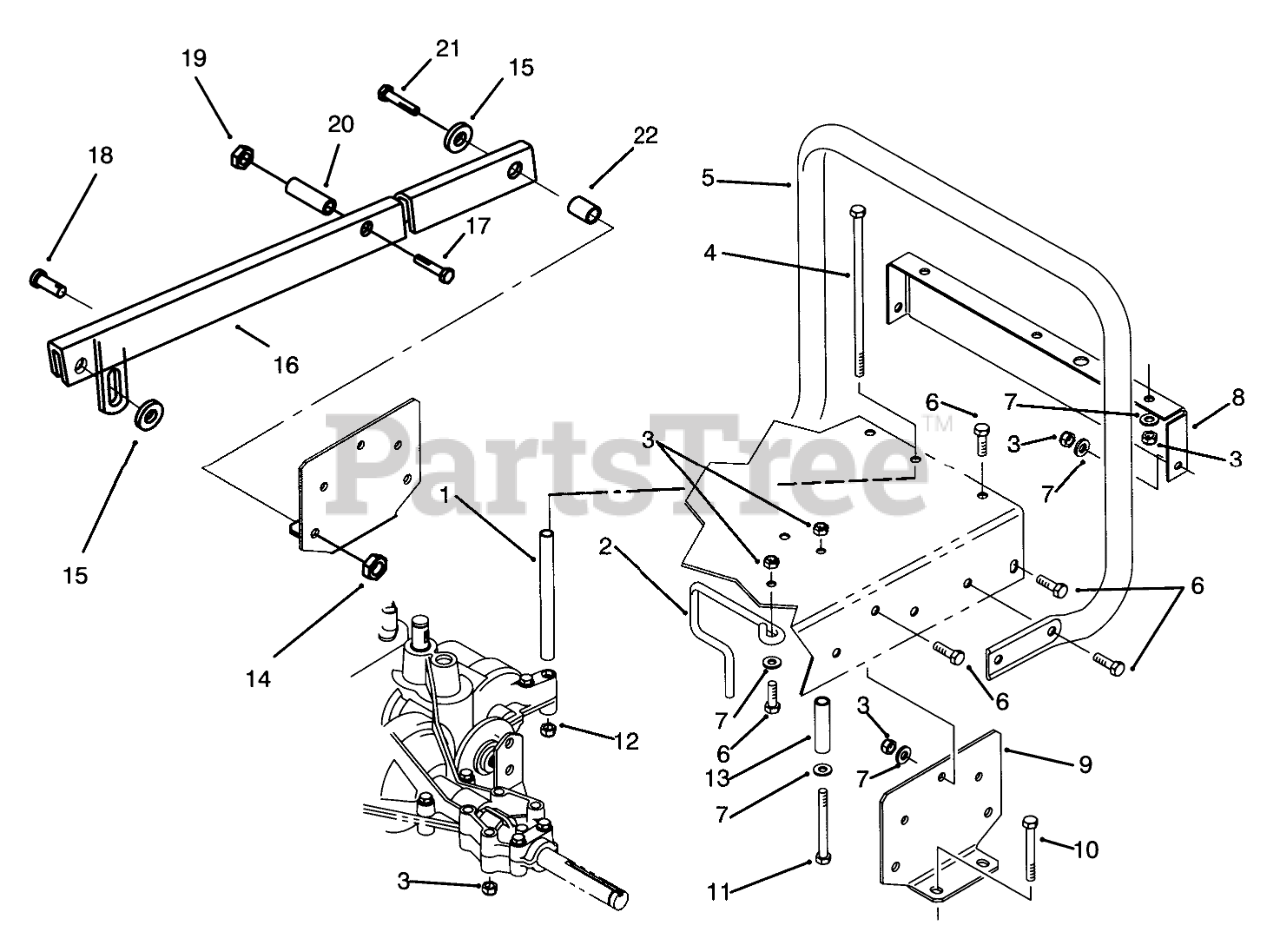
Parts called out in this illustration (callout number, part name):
1	SPACER-TRANSAXLE SUPT
2	GUIDE-ENG BELT
3	NUT-LOCK, NI
4	SCREW-HH
5	Standbar
6	SCREW-HH
7	WASHER-PLAIN
8	Frame-Rear
9	Support-Axle
10	SCREW-HH
11	SCREW-HH
12	NUT-LOCK, NI
13	SPACER-SPLIT TUBE
14	NUT-LOCK, NI
15	WASHER-FLAT
16	Arm-Suspension R.H.
17	SCREW-HH
18	PIN-CLEVIS
19	NUT-LOCK, NI
20	SPACER-SPLIT TUBE
21	SCREW-HH
22	PIN-SUPT ARM
